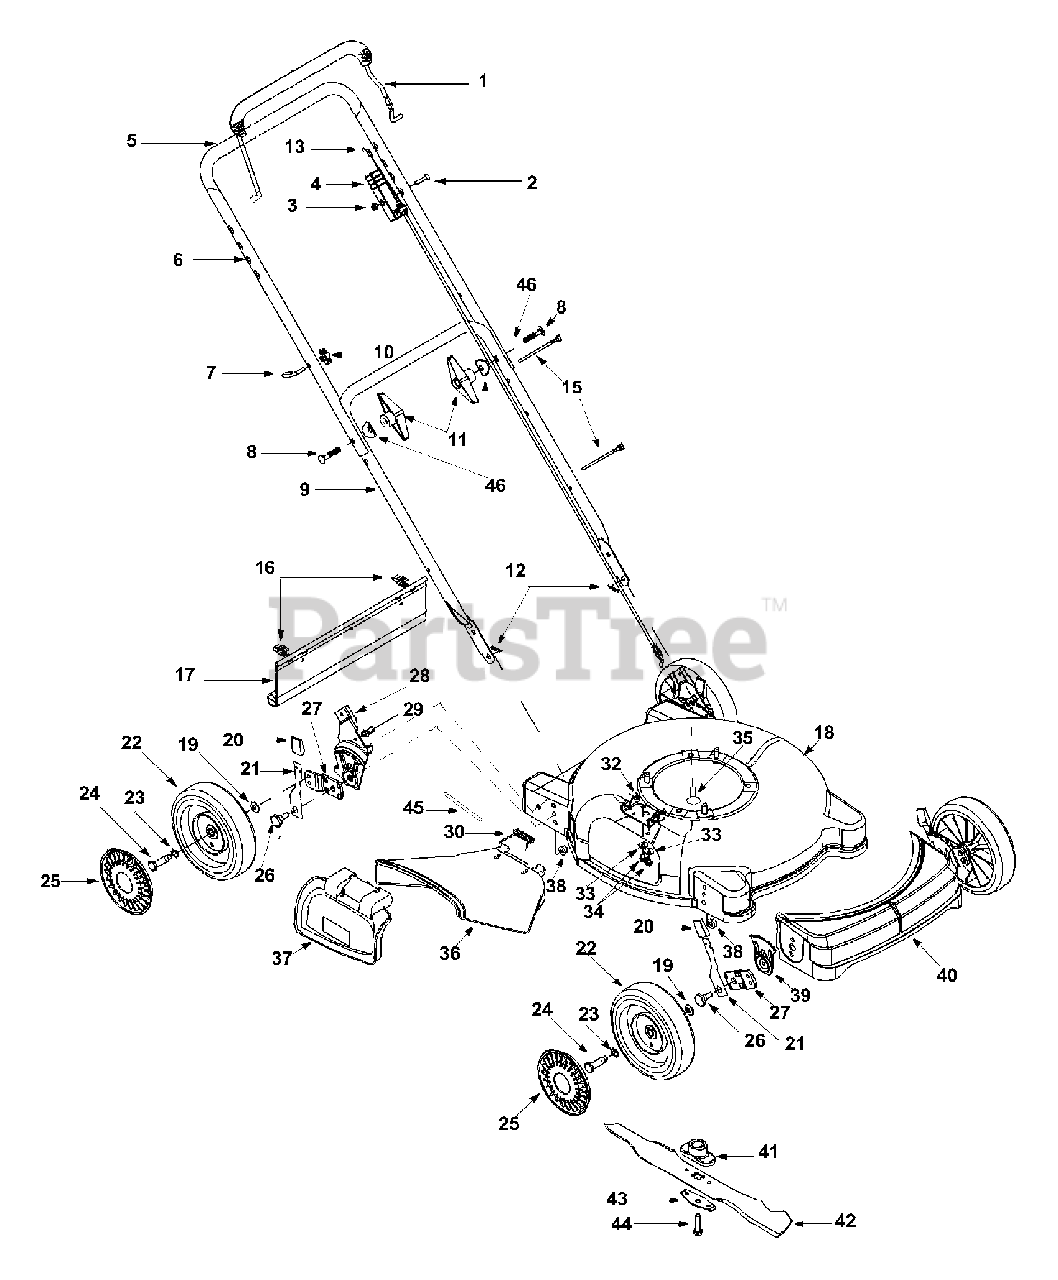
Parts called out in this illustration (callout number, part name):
1	Control Handle Assembly
2	Oval C-Sunk Screw
3	Hex Lock Nut
4	Control Housing
5	Foam Grip
8	Carriage Bolt
10	Wing Nut
11	Hand Knob
12	Hairpin Clip
13	Control Cable 40.5"
15	Cable Tie
16	Hinge Clip
17	Trail Shield
20	Knob: Height Adjustment
21	Lever: Spring
22	Wheel Assembly
23	Wave Washer
24	Axle Bolt
25	Hubcap: Radial Spoke, Yellow
26	Shoulder Bolt
29	Stake Bolt
30	Torsion Spring
33	Bell Washer
34	Hex Washer Hd. TT Screw
35	TT Sems Screw
36	Chute Deflector
37	Mulching Plug Assembly
38	Hex Lock Nut
39	Height Adjustment Plate
40	Cover: Front End
41	Blade Adapter
42	20" Mulching Blade
43	Blade Bell Support
44	Hex Bolt
45	Hinge Pin
46	Saddle Washer
